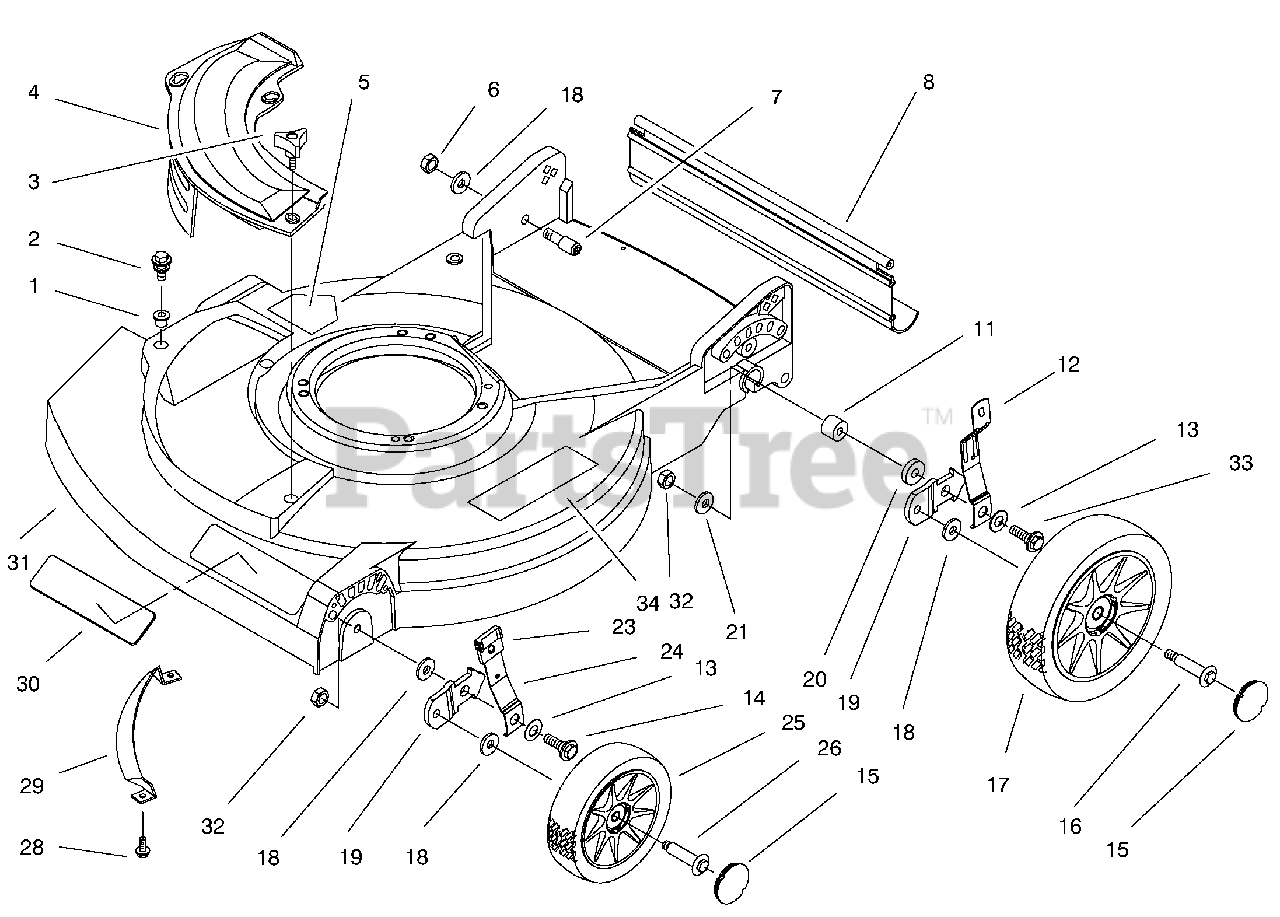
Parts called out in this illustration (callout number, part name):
2	Screw-Thread Forming
3	Knob
4	Cover- Plate, Mulch
5	Decal-Danger (English)
7	Bolt-Shoulder
8	Shield-Trailing
12	Spring Arm Assembly
13	Washer-Belleville
14	Bolt-Shoulder
16	Bolt-Wheel
17	Wheel Assembly 8"
18	Washer-Wheel Bolt
19	Bracket-H. O. C.
23	Knob-Spring Arm
24	Spring Arm Assembly
25	Wheel-6"
26	Bolt-Wheel
29	Bar-Toe
31	Housing-21" (Incl. Ref.#5 & 34)
32	Nut-Lock
33	Bolt-Shoulder
34	Decal-Warning
